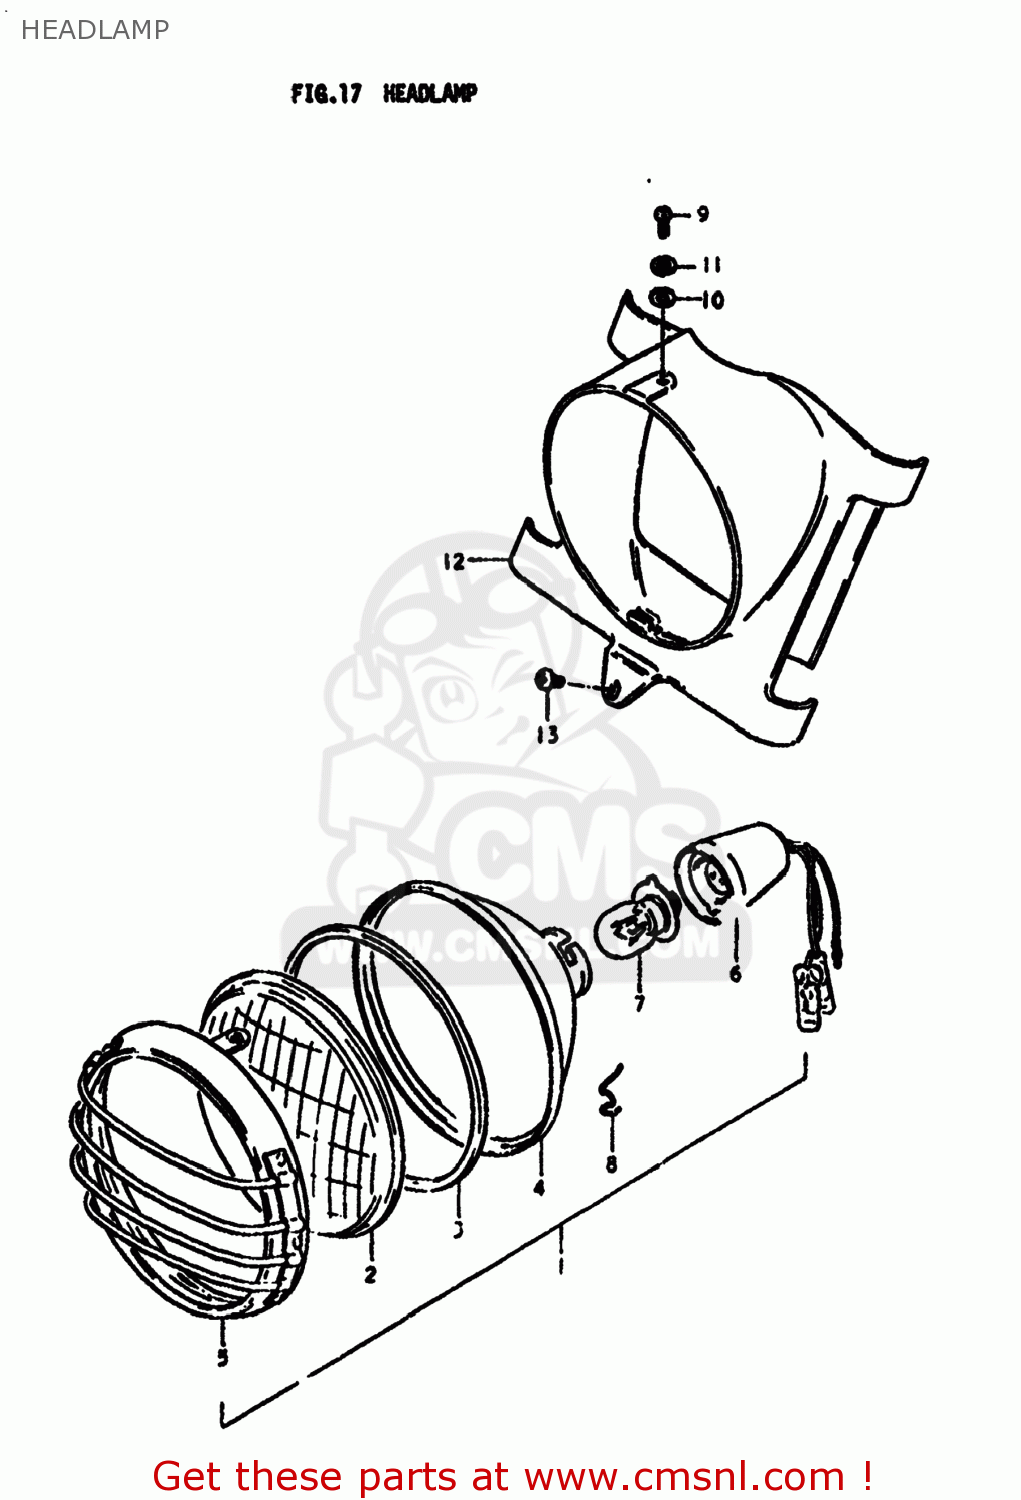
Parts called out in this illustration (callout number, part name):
1	HEADLAMP ASSEMBLY
2	LENS,HEADLAMP
3	GASKET,HEADLAMP LENS (NAS)
4	REFLECTOR,HEADLAMP
5	RIM,HEADLAMP
6	SOCKET,HEADLAMP
7	BULB(6V15/15W/STANLEY,A3598HA)
8	SPRING
9	SCREW
10	WASHER
11	LOCK WASHER
12	HOUSING,HEADLAMP
13	SCREW
